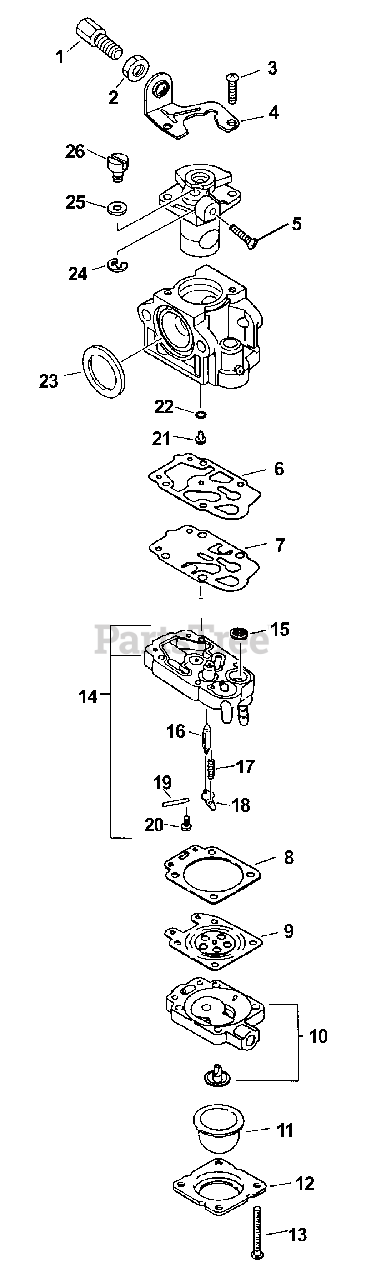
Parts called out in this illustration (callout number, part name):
1	NUT, CABLE ADJUST
4	BRACKET, THROTTLE CABLE
5	SCREW, IDLE ADJUST
6	GASKET, PUMP
7	DIAPHRAGM, PUMP
8	GASKET, METERING
9	DIAPHRAGM, METERING
10	PURGE BASE ASSY
11	BULB, PURGE
12	RETAINER, PURGE BULB
13	SCREW, PUMP COVER
14	BASE, PURGE
15	STRAINER
16	VALVE, INLET NEEDLE
17	SPRING, METERING LEVER
18	LEVER, METERING
19	PIN, METERING LEVER
20	SCREW, METERING LEVER PIN
21	JET, MAIN
23	SEAL
24	RING, RETAINING
26	REPAIR KIT
26	DIAPHRAGM/GASKET KIT
